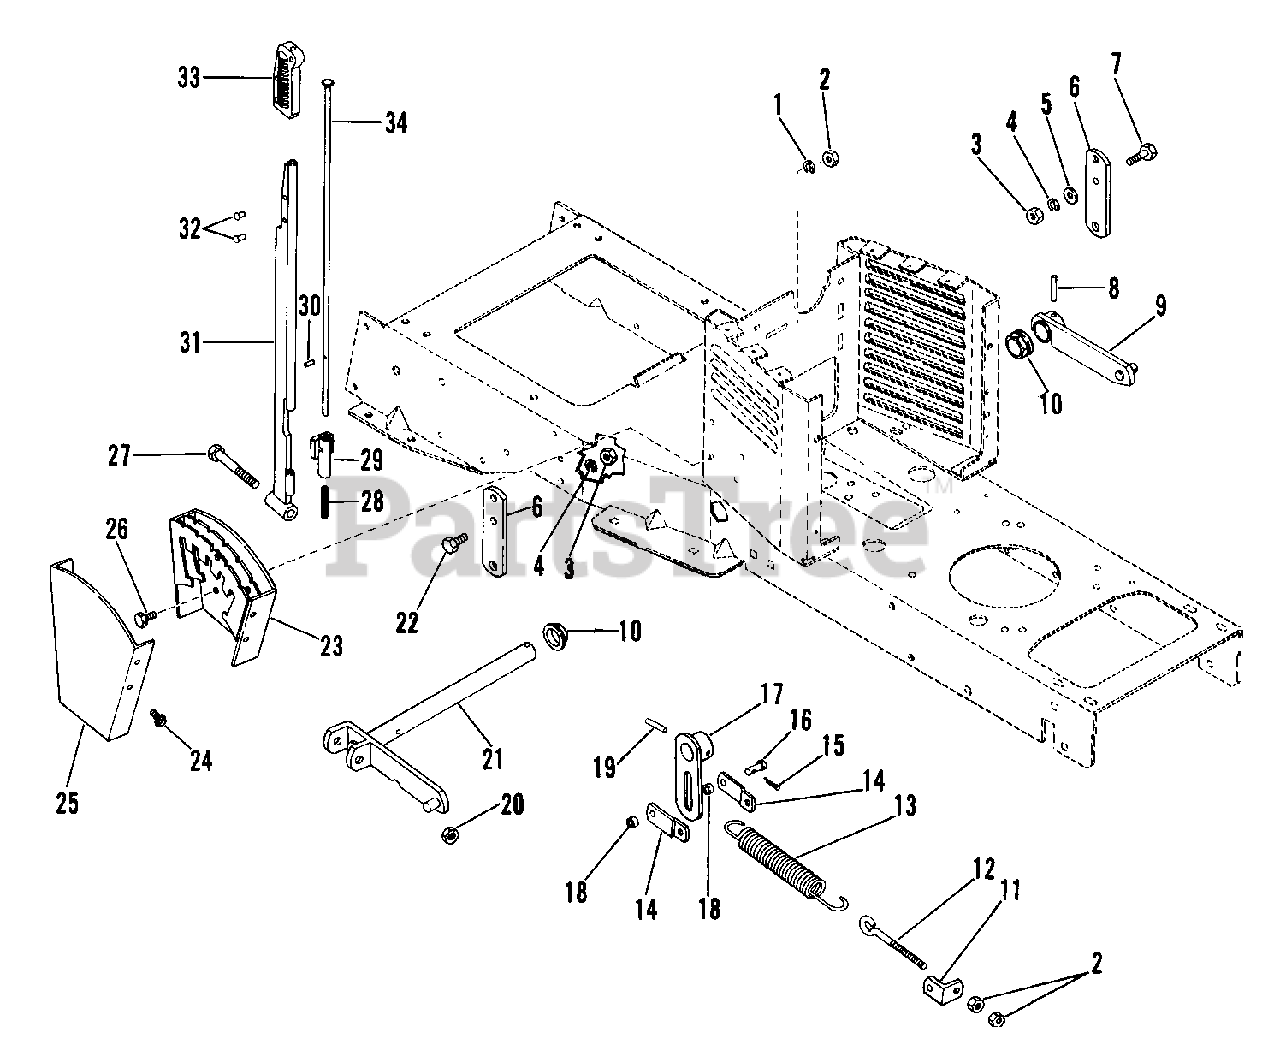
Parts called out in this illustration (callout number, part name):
1	WSHR-LK .312X.097 PL HVY
2	NUT-HEX .312-18
3	NUT-HEX .375-16
4	WSHR-LK .375X.115 HVY PL
5	WSHR-FL-STL.406X.812X.065PL
6	REAR ATTACHMENT HANGER
7	BLT-HEX .38-16X1.25 PL GR5
8	PIN-GRV .250X1.50 TP A
9	LIFT ARM
10	FLANGE BUSHING
10	BSHG-FLG 1.000X1.25X.49X1.56HX
11	SPRING ANCHOR
12	EYE BOLT
13	SG-TENS .162X1.25X8.25 WLD 25
15	PIN-COTR .09X.75 PL
16	CLEVIS PIN
17	COUNTER BALANCE ARM
18	SPACER BUSHING .5 X .32 X .21
19	PIN-ROLL .250X1.50
20	NUT-LK-NYL .50-13 GR 5 PL
21	LIFT PIVOT
22	BLT-HEX .38-16X1.00 PL GR5
23	SPRING SHANK
24	SCR-TAP .312-18X.50 HWH PL TR
25	QUADRANT SHIELD
26	BLT-HEX .31-18X.75 PL GR5
27	BLT-HEX .50-13X3.25 GR5
28	SG-COMP .042X.36X2.00 WLD5.15
29	QUADRANT CATCH
30	PIN-ROLL .093X.50
31	LIFT HANDLE
32	RVT-POP .187X.402 DOME ST
34	CLEVIS PIN
